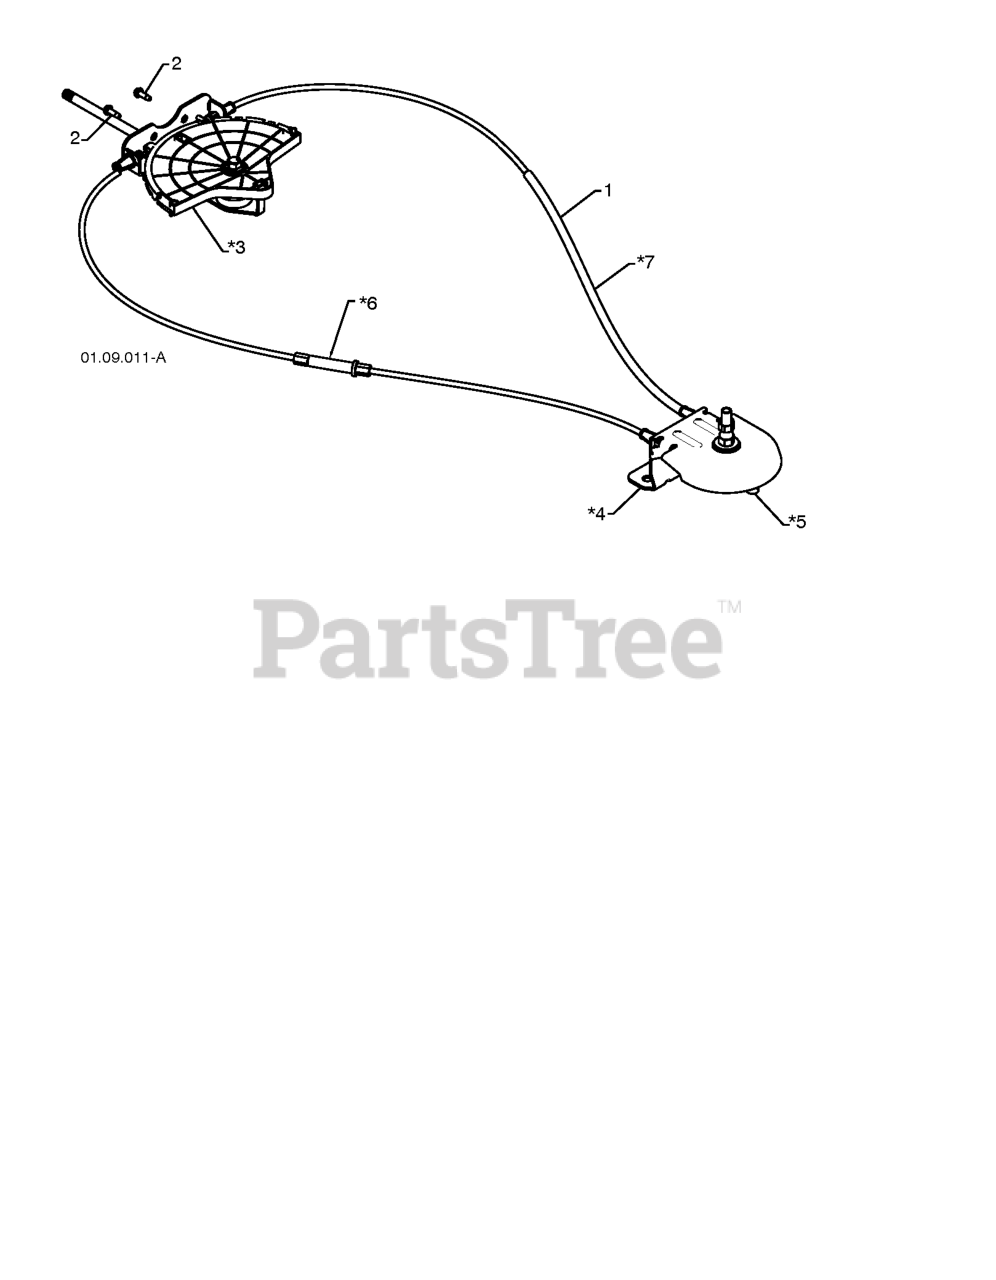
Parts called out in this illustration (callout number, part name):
1	RB LEVER.CABLE.ASM.ROTATR.PLTD
2	SCREW #10-24 X 5/8
3	CHUTE.ROT.HEAD.SERVICE
4	SNOW.PIVOT.BRKT.GRY.SERVICE
5	SNOW.PIVOT.PULLY
6	SNOW.CABLE.ASM.ADJUSTABLE.GRAY
7	SNOW.CABLE.ASM.SERVICE
